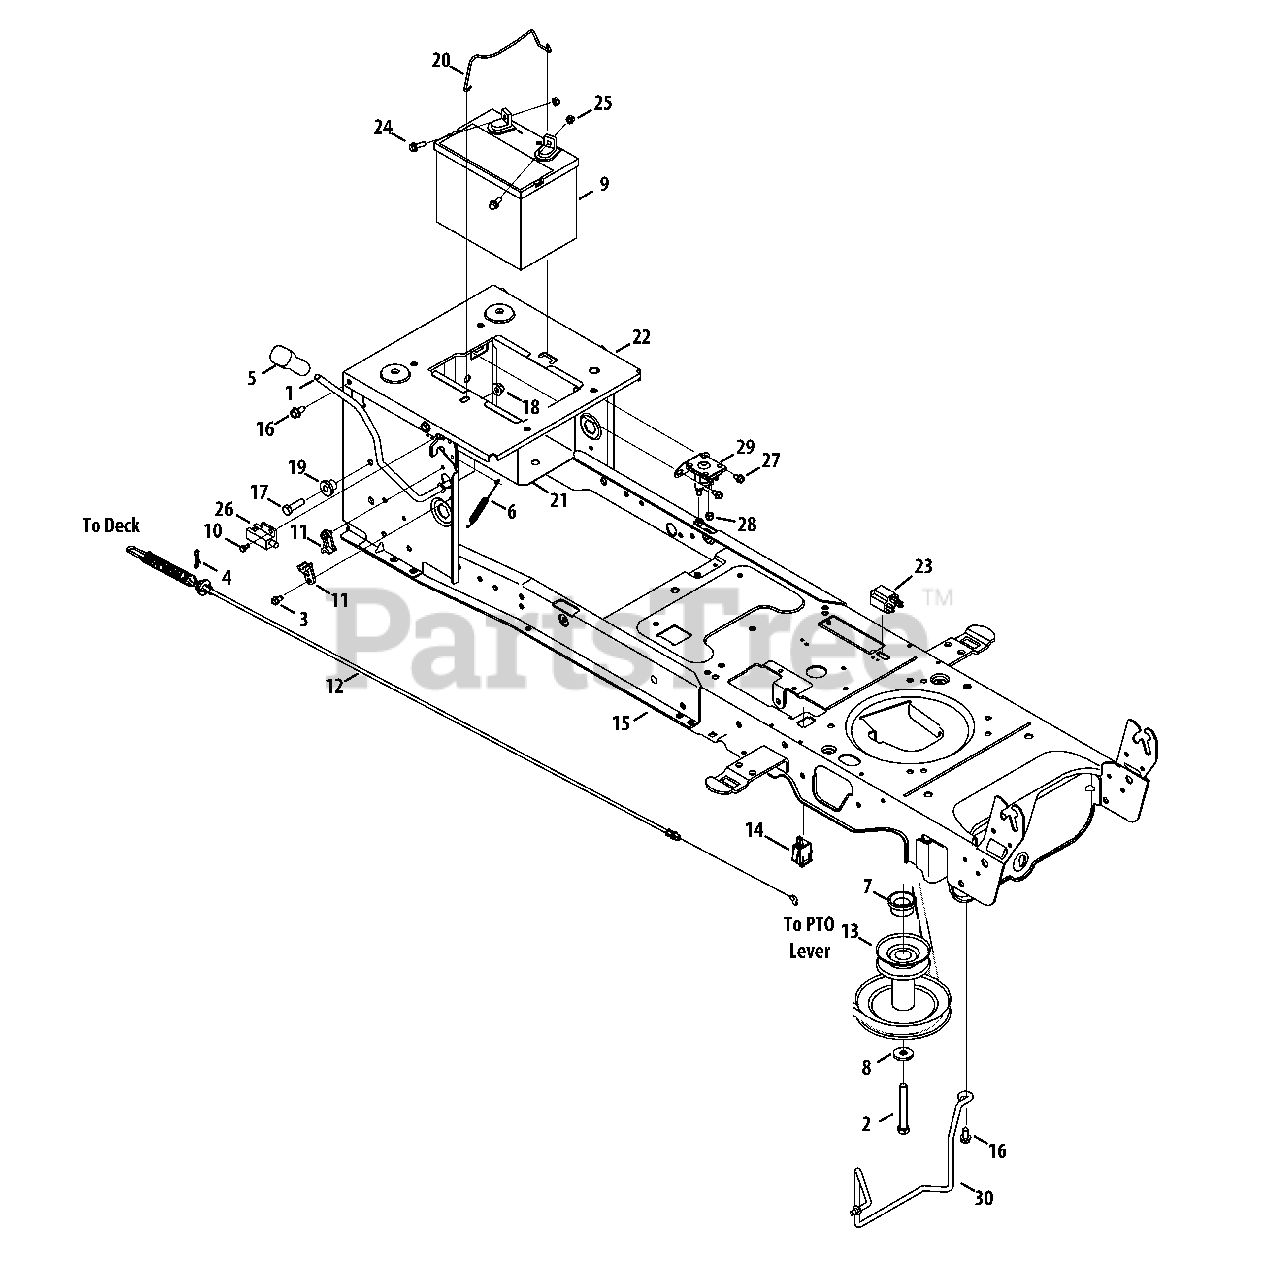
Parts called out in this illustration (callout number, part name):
1	H&le Ass’y, PTO
2	Hex Screw, 7/16-20, 3.50, Gr5
3	Screw, Self-tapping, 1/4-20, 0.50
4	Pin, Cotter, Bow-Tie 72
5	Grip, H&le, Cub
6	Spring, Ext, .38 Dia x 5.6
7	Spacer, 1.010 x 1.40 x .825
8	Washer, Flat, .450 x 1.250 x .164
10	Screw, Shoulder, #10-32, .500
11	Bearing, PTO
12	Cable, Engag, Deck
13	Pulley, Engine, 3.56 x 6.12 Dia.
14	Switch, Plunger, Snap Mount
15	Frame Ass’y, Lower
16	Screw, Self-tapping, 5/16-18, .750,
17	Hex Screw, 3/8-16, 1.25, Gr5
18	Nut, Flange Lock, 3/8-16, Grf,
19	Spacer, Shoulder, .38 x 1.0 x .70
20	Rod, Battery
21	Tray, Battery
22	Bracket, Frame, Seat
23	Switch, 3-Pole
24	Hex Flange Screw, 1/4-20, .75, Gr5
25	Nut, Sems, 1/4-20
26	Switch, Interlock
27	Screw, Self-tapping, 1/4-20, 0.375,
28	Nut, Flange Lock, 1/4-20, Grf,
29	Solenoid, 12V, 100 Amp, 4 term
30	Rod, Keeper
